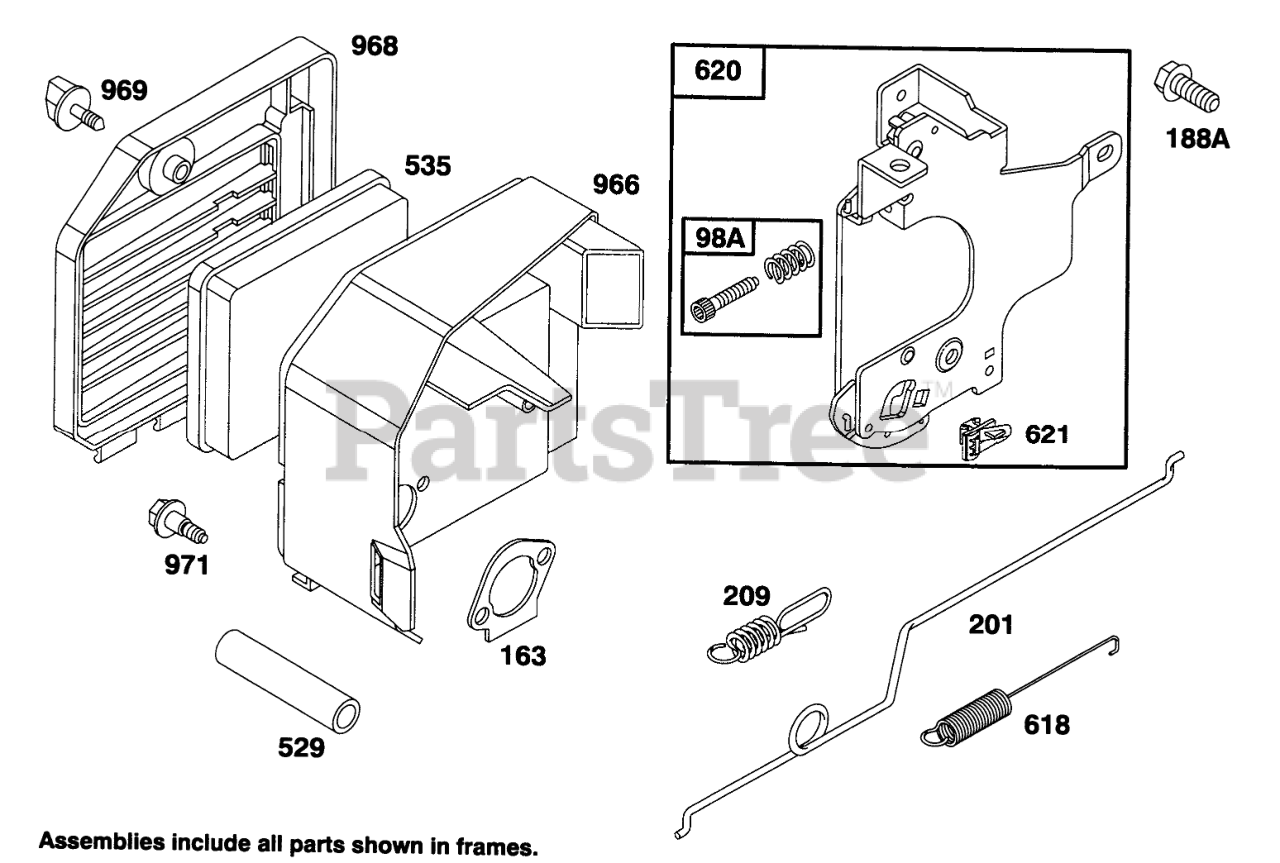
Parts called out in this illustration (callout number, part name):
8	BREATHER GASKET
98A	SPEED ADJUST. SCREW ASM
116	O-Ring
163	AIR CLEANER GASKET
188A	Screw-Hex Head
201	GOVERNOR LINK
209	GOVERNOR SPRING
529	BREATHER TUBE
535	FILTER ELEMENT
618	RETURN SPRING
620	CARBURETOR BRACKET
621	STOP SWITCH
966	AIR CLEANER BASE
968	AIR CLEANER COVER
969	AIR CLEANER SCREW
971	AIR CLEANER SCREW
